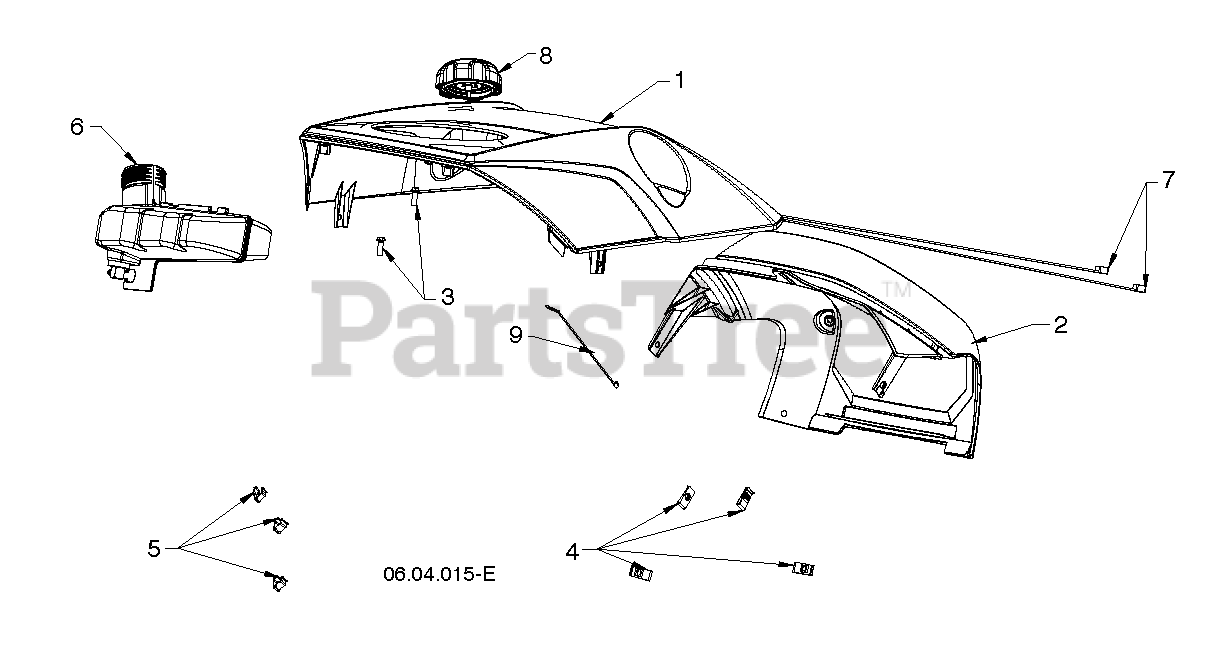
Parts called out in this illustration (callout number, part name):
1	COVER.TOP.SSST.ORANGE
2	COVER.REAR.UPPER.GREY
3	SCREW.HX.13X.750
6	TANK.GAS.12.SINGLE.STAGE.SNOW
7	TIE.CABLE.24.5X.29.NYLON.WHITE
8	CAP.2.25'.VENTED.RATCHET.EPA
9	WIRE.TIE
